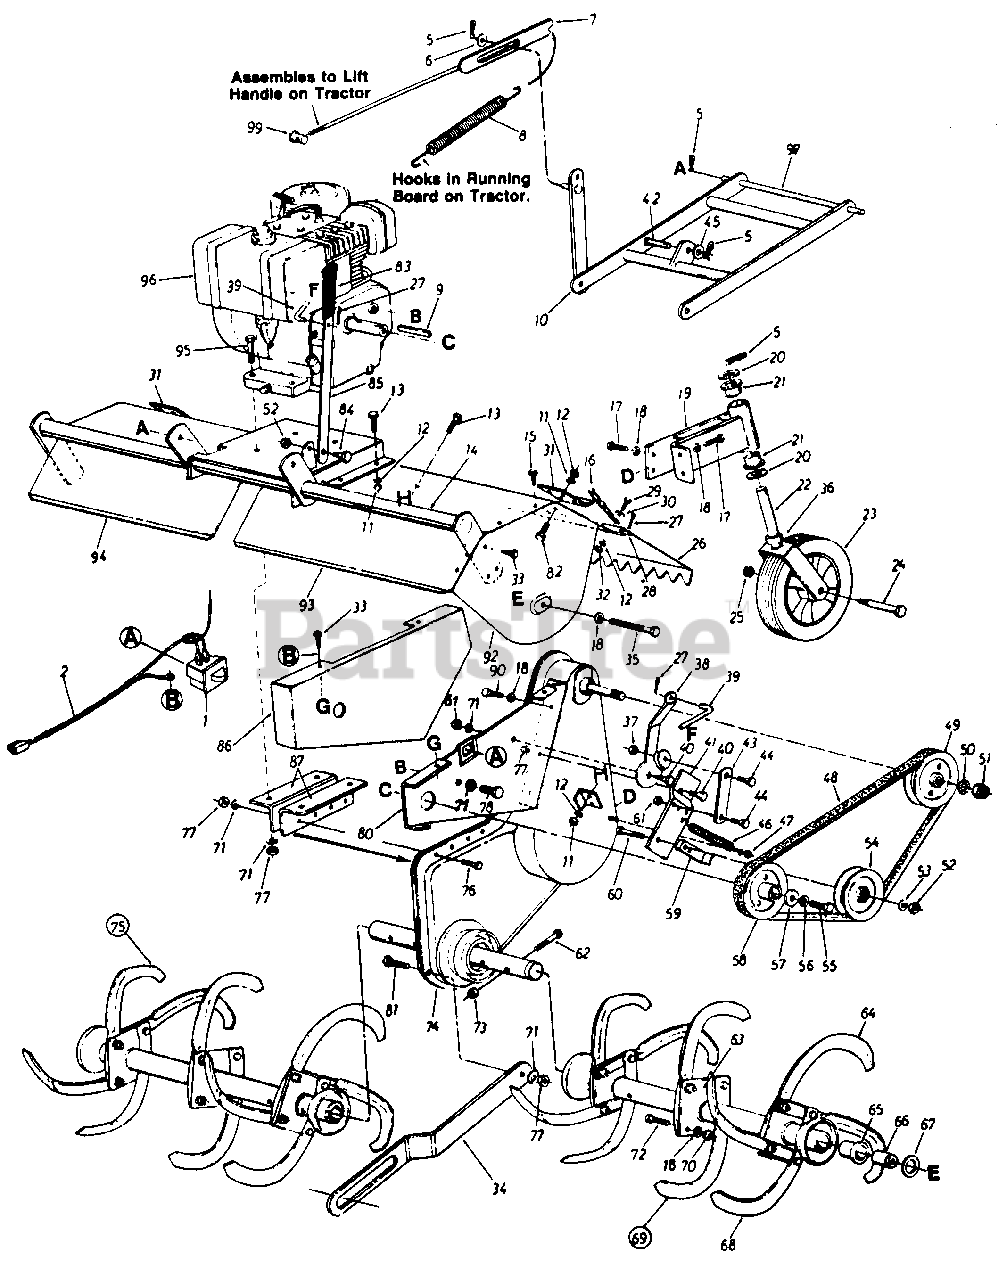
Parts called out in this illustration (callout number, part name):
1	Safety Switch
2	Wire Harness
5	Internal Cotter Pin
6	Fl-Wash. 1/2" I.D. x .93" O.D.
9	Sq. Key 1/4" x 1/4" x 2.00" Lg.
12	L-Wash. 1/4" I.D.
13	Hex Bolt 1/4-28 x .62" Lg.
16	#2 Dog Chain x 20" Lg.
17	Hex Wash. Hd. Self-Tap Scr. 3/8-24 x .75" Lg.
18	L-Wash. 3/8" I.D.
21	Flange Bearing 3/41' I.D. x 1.00" O.D.
24	Shoulder Bolt .623" I.D. x 3.62" Lg.
25	Hex Cent. L-Nut 7/16-14 Thd.
28	L.H Flap Rod
29	Hex Bolt 1/4-20 x .62" Lg.
30	Fl-Wash. 1/4" I.D.
33	Hex Wash. Hd. Self-Tap Scr. 1/4" x.62" Lg.
36	Spacer .752" I.D. x 1.25" O.D.
37	Hex Cent. L-Nut 5/16-18 Thd.
40	Shoulder Bolt 7/16" Dia. x 1.75" Lg.
45	Fl-Wash. 50" I.D. x 1.0" O.D. x .0
46	Extension Spring .62" O.D. x 6.12" Lg.
47	Hex Crown Nut 3/8-24 Thd.
48	V"-Belt (Kevlar)
49	1/2" "V"-Pulley 4.75" O.D. x .625" Bote
50	L-Wash. 5/8" I.D.
51	Hex Ins. L-Nut 5/8-18 Thd.
52	Hex Cent. L-Nut 3/8-16 Thd.
53	Fl-Wash. 3/8" I.D.
54	Idler Pulley 4.0" O.D.
55	Hex Bolt
56	L-Wash. 7/16" I.D.
57	Fl-Wash. 7/16" I.D. x 1.38"
58	1/2" "V"-Pulley .475" O.D. x 1.00" Bore
61	Hex Cent. L-Nut 5/16-18 Thd.
62	Hex Bolt 7/1614 X 2.00" Lg.
66	Spacer
67	Thrust Wash. 1/2" I.D. x 1.55"
71	L-Wash. 5/16" I.D.
72	Hex Bolt 3/8-24 X 1.5" Lg.
73	Hex Cent. L-Nut 7/16-14 Thd.
77	Hex Nut 5/16-18 Thd.
78	Hex Bolt 5/16-24 x .62"
80	Clutch Support Bracket
81	Shld. Bolt .435 Dia. x .265 5/1 6-1 8 Thd.
82	Hex Bolt 1/4-28 x .75" Lg.
83	Plastic Grip
84	Shoulder Bolt .498 Dia. x .212 Lg.
96	8 H.P. Engine
97	Hitch Rod
99	Ferrule
04975-0637	PLATE ASSY-SIDE-LH - POWDER BLACK (0637)
04978-0637	SUPPORT-SWIVEL WHE - POWDER BLACK (0637)
04983-0637	L.H.-Tine Shield - POWDER BLACK (0637)
14298-0637	SHROUD-CLUTCH SUP - POWDER BLACK (0637)
